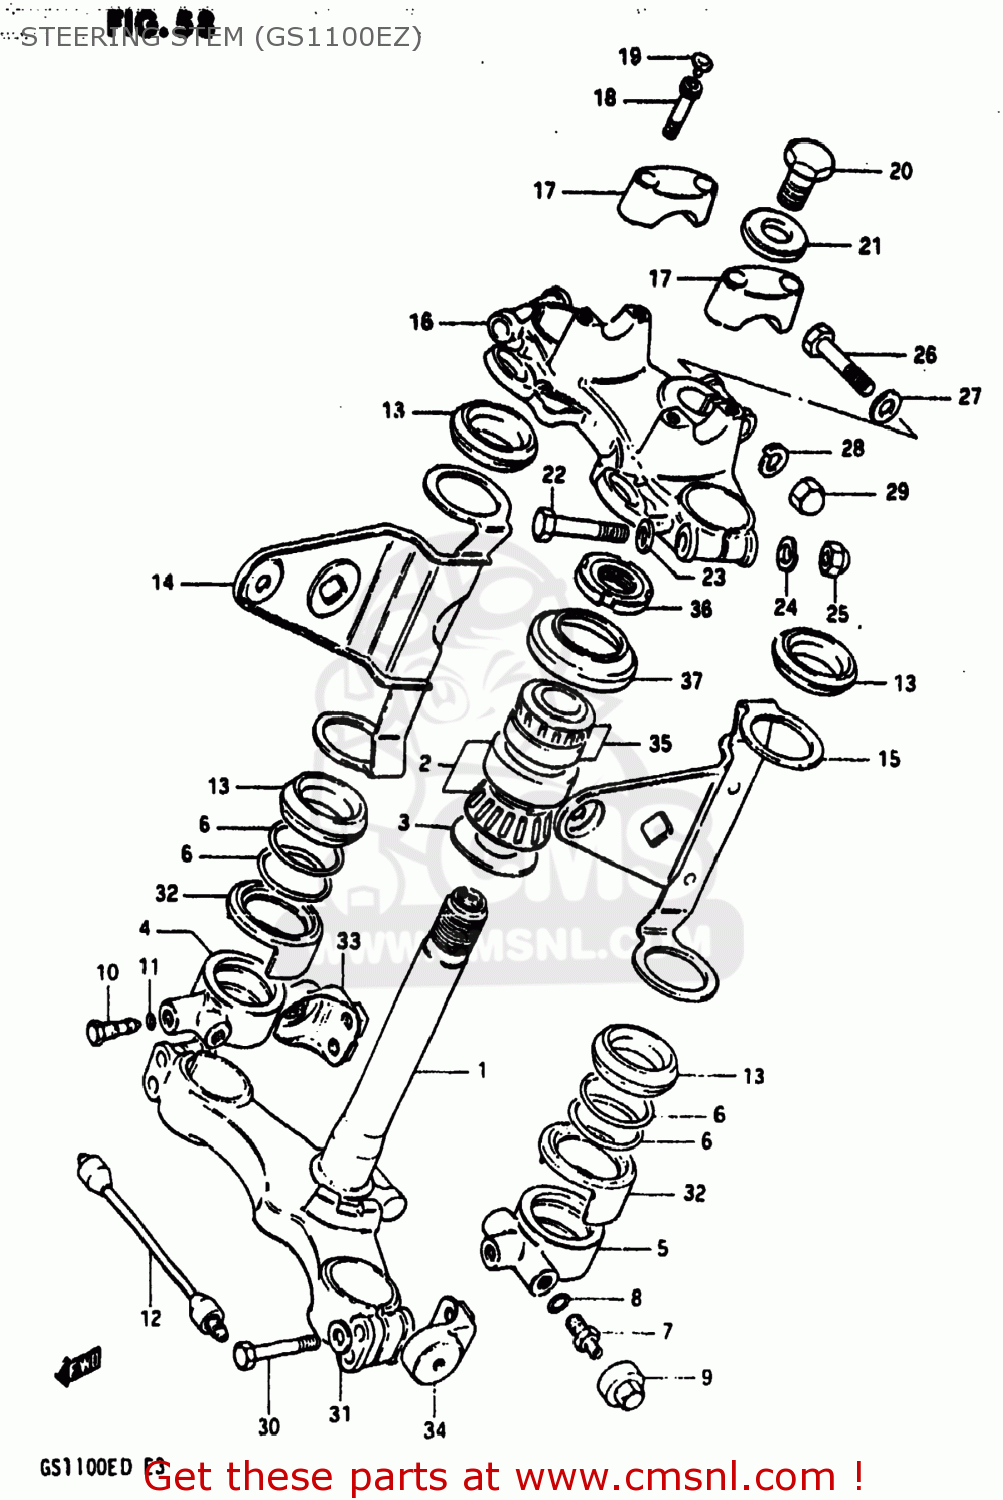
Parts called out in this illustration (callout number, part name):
1	STEM,STEERING
2	BEARING
3	WASHER,THRUST
4	JOINT,AIR,RIGHT
5	BRACKET,FORK CONNECTING
6	O RING
7	VALVE
8	O RING
9	CAP,VALVE
10	VALVE,STOP
11	O RING
12	HOSE,FORK CONNECTING
13	CUSHION,HEADLAMP BRACKET
14	BRACKET,HEADLAMP,RIGHT
15	BRACKET,HEADLAMP,LEFT
16	HEAD,STEERING STEM
17	HOLDER,HANDLEBAR
18	BOLT
19	CAP(OD:14.5)
20	SUZUKI
21	SUZUKI
22	BOLT 10X55
23	WASHER
24	LOCK WASHER
25	NUT 10MM
26	BOLT 8X50
27	WASHER
28	LOCK WASHER
29	NUT,M8X1.25X12
30	BOLT 8X55
31	WASHER
32	BRACKET,REFLECTOR
33	COVER,FORK BRACKET,RIGHT
34	COVER,FORK BRACKET,LEFT
35	TAPER,ROLLER BEARING
36	NUT,STEERING STEM
37	DUST SEAL,STEERING UPR
